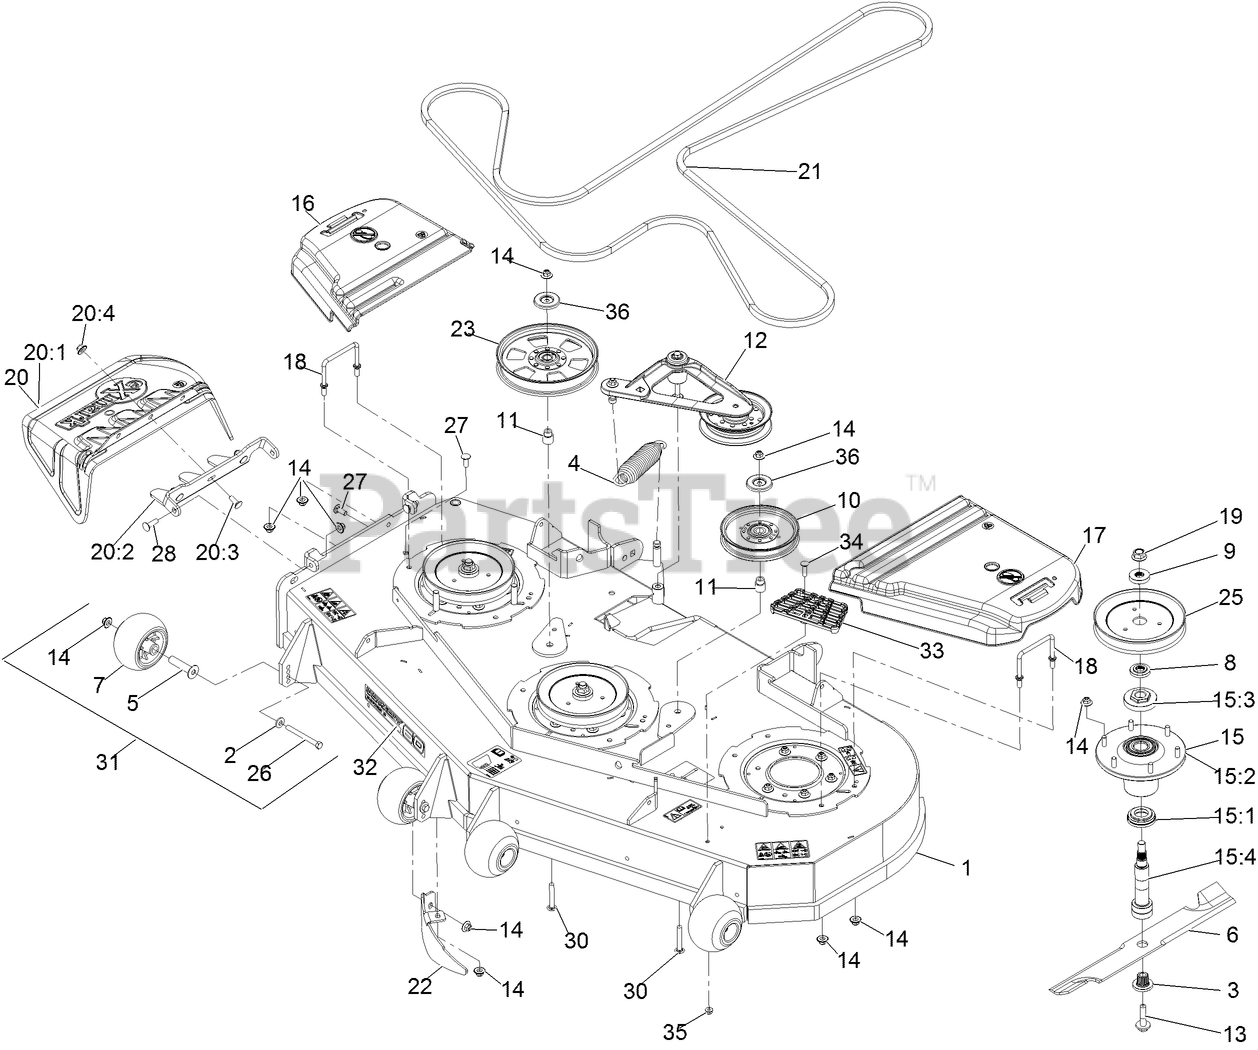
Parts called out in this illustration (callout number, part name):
1	DECK ASM,W/DECALS 60
2	WASHER-BELLEVILLE
3	BUSHING,SPLINED
4	SPRING-EXTENSION
5	AXLE, ROLLER
6	Blade-Extreme 2, 20.50"
7	ROLLER-SCALP, ANTI
8	SPACER,SPLINED STEPPED
9	SPACER,SPLINED
10	IDLER-PULLEY
11	BUSHING-IDLER
12	DECK IDLER ASM
13	SCREW,SEMS 1/2-20 X 2.19
14	Nut-Nyloc 3/8-16 Flg
15	ASM,SPINDLE HOUSING
15:1	GUARD,BOTTOM
15:2	ASM,CUTTER HOUSING
15:3	NUT, SPINDLE 7/8-14
15:4	SPINDLE,DOUBLE SPLINE
16	COVER-BELT, RH
17	COVER-BELT, LH
18	WIREFORM-COVER
19	NUT-FLANGE, CENTERLOCK
20	ASM,DISCHARGE CHUTE
20:1	CHUTE,DISCHARGE
20:2	BRACKET,DISCHARGE CHUTE
20:3	SCREW-CARR
20:4	Nut-Nyloc 3/8-16 Flg
22	DOGLEG - LZ60
23	PULLEY-IDLER, FLAT
25	SHEAVE,BLADE DRIVE 7.25
26	SCREW-HH 3/8-16 X 3 3/4 GR 8
27	SCREW-CARR
28	Bolt-Carriage 3/8-16 X 1 1/4
30	SCREW-CARR
31	KIT, ANTI-SCALP ROLLER
32	DECAL, 606
33	STEP-DECK
34	Bolt-Carriage 5/16-18 X 1 1/4
35	NUT-HF, NI
36	SHIELD-DUST
